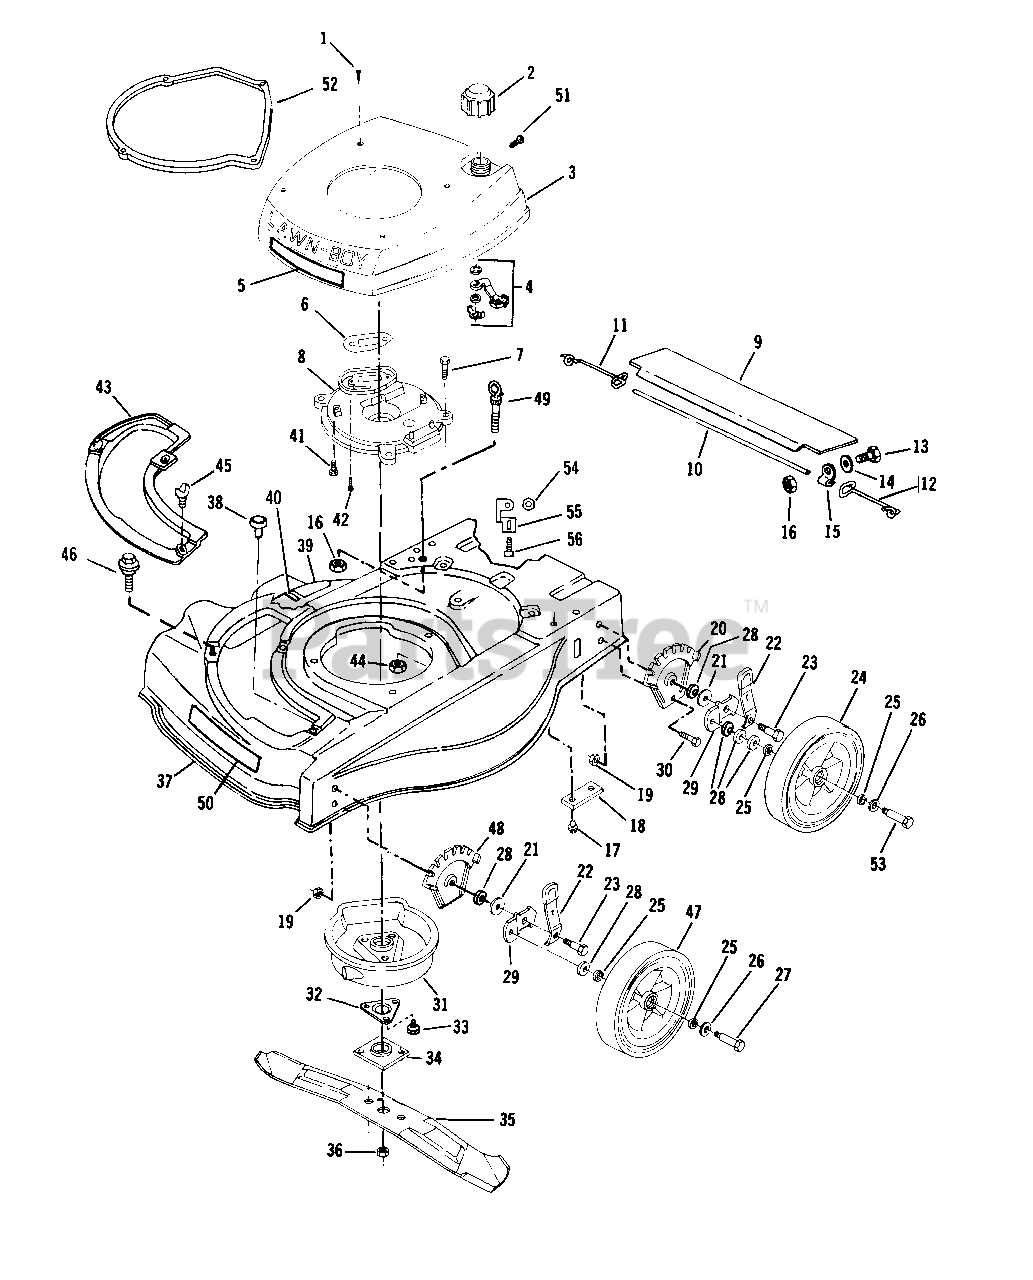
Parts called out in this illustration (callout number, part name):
1	Screw
2	Fuel Cap Assembly
3	Shroud Assembly
4	Fuel Shut-Off Assembly
5	Decal-Special
6	Gasket
7	Screw-Muffler Plate to Hsg.
8	Plate-Muffler
9	Shield-Trailing
10	Rod-Trailing Shield
11	Spring-R.H.
12	Spring-L.H.
13	Screw-Trailing Shield
14	Washer-Trailing Shield
15	Clamp-Trailing Shield
16	Nut-Trl. Shield and Eyebolt
17	Screw-Handle Bracket
18	Plate-Hdl. Brkt. to Housing
19	Nut-Hgt. Adjust and Back-up Plate
20	Plate-Height Adjust-Rear
21	Washer-Wheel Mtg. Brkt.
22	Knob and Spring Assembly
23	Bolt-Wheel Bracket to Knob and Spring Assembly
24	Wheel-Rear
25	Washer-Felt
26	Washer-Wheel Bolt Head
27	Bolt-Shoulder, Wheel-Front
28	Washer
29	Bracket-Wheel Height Adjust
30	Screw-Height Adjust Plate
31	Muffler Cover Assembly
32	Support-Crankshaft
33	Screw-Crankshaft Support
34	Collar and Plate Assembly
35	Blade-21"
36	Nut
37	Housing Assembly
38	Grommet
39	Decal-Blade Contact Warning
40	Decal-Discharge Area
41	Screw-Muffler Plate to Block
42	Screw-Muffler Plate to Block
43	Cover Plate
44	Nut-Muffler Plate to Housing
45	Wing Screw
46	Screw-Plate and Chute Mounting
47	Wheel-Front
48	Plate-Height Adjust-Front
49	Eyebolt
50	Decal-Headliner
51	Screw-Shroud to C.D. Bracket
52	Spacer-Shroud to Base
53	Bolt-Shoulder, Wheel-Rear
54	Nut-Baffle Bracket
55	Bracket-Baffle
56	Screw-Baffle Bracket
